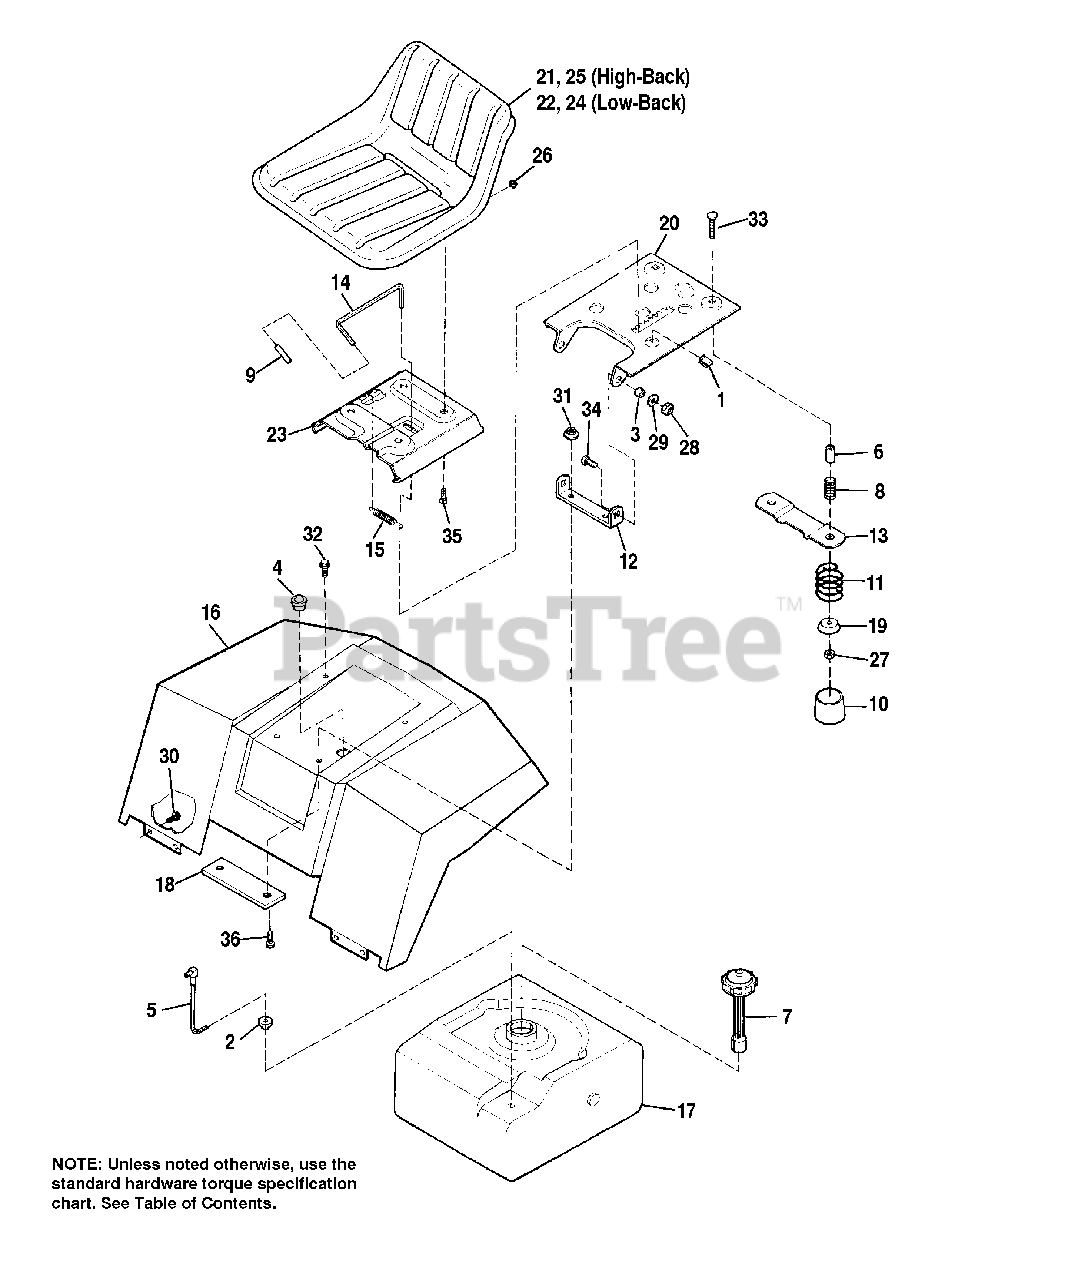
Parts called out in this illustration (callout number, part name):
1	CLIP, Speed
4	BUSHING, Snap
5	ELBOW & TUBE ASSY.
7	CAP, Fuel Gauge
8	SPRING, Compression
9	HANDLE, Grip
10	COVER, Spring
11	SPRING, Compression
12	BRACKET, Seat Pivot
13	PLATE, Switch
14	LEVER, Seat Release
15	SPRING, Extension
16	SEAT DECK, Orange
16	SEAT DECK, Red
17	TANK, Fuel
18	PLATE, Reinforcement
19	WASHER, Plain
20	SUPPORT, Seat Pivot
21	SEAT, High-Back
22	SEAT, Low-Back
23	BRACKET, Seat Slide
24	COVER, Low-Back Seat
25	COVER, High-Back Seat
27	NUT, Hex, Nylon Lock, 5/16-18
28	NUT, Hex, Nylon Lock, 3/8-16
29	WASHER, Plain, 13/32
30	SCREW, Taptite, 1/4-20 x 1/2
31	NUT, Hex, Flange, Whizlock, 5/16-18 x 1/2
32	SCREW, Taptite, 5/16-18 x 5/8
33	CARRIAGE BOLT, 5/16-18 x 2
34	CARRIAGE BOLT, 3/8-16 x 1
35	BOLT, Hex, Whizlock, 5/16-18 x 5/8
36	SCREW, Truss Hd., Torx drive, 3/8-16 x 1
